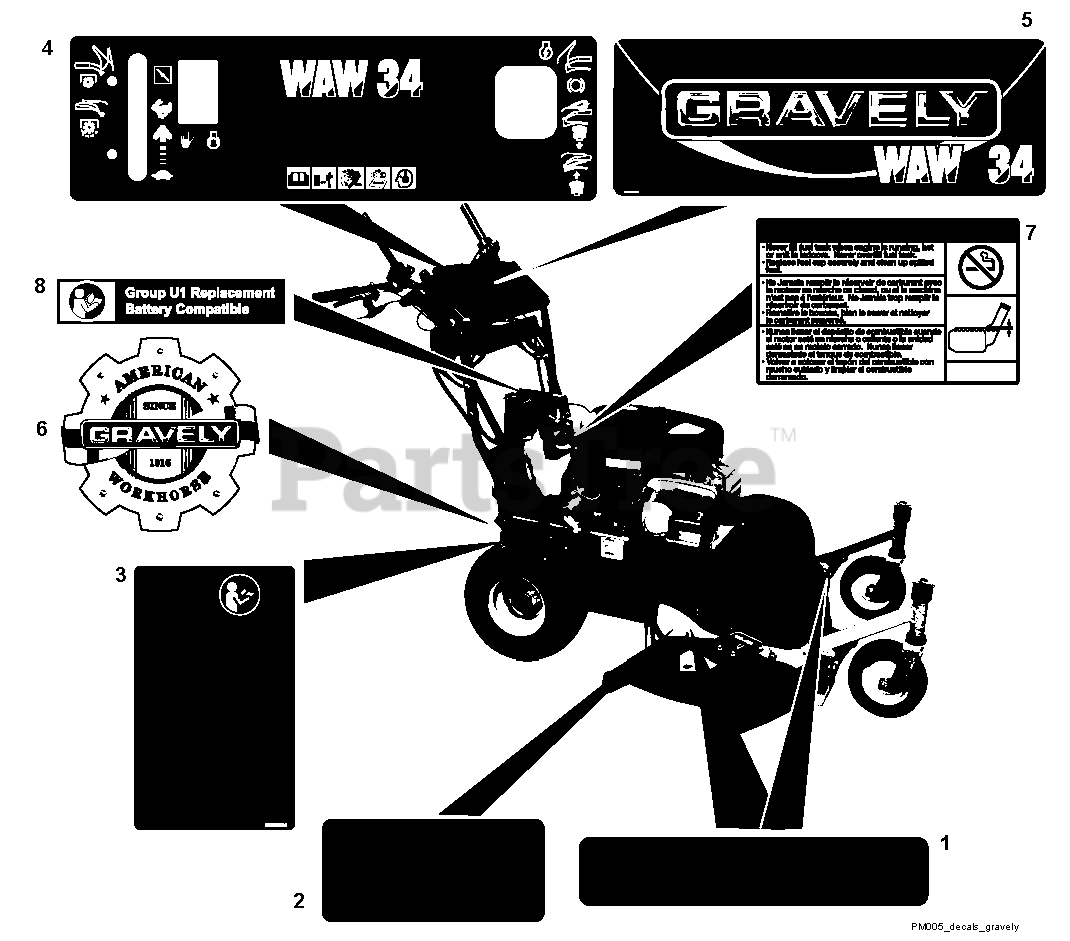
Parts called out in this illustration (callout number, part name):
1	Decal, Mower Pan Head Danger
2	Decal, Warning
3	Decal, Bilingual Danger
4	Decal, WAW 34 Operational
5	Decal, WAW 34 Gravely Dash
6	Decal, Made In America
7	Decal, Fuel, Warning
8	Decal, U1 Battery Replacement
